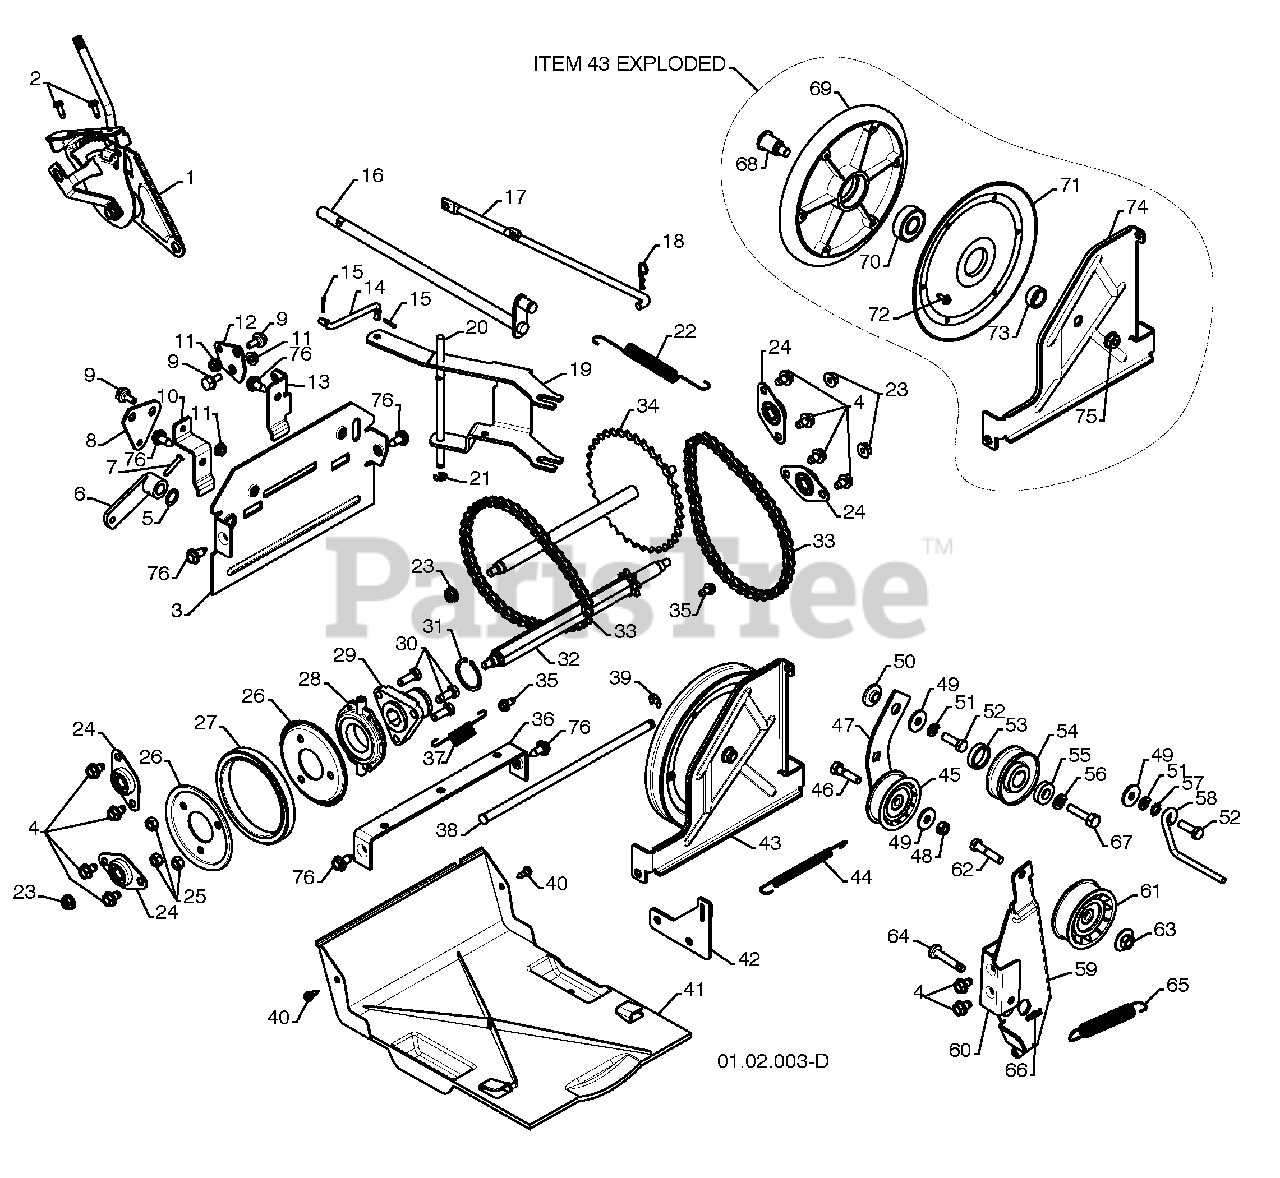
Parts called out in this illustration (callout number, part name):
1	SPEED SELECTOR ASSEMBLY
2	SCREW 10-24 X .625
3	END PLATE
4	SCREW 5/16-18 X .50
5	WASHER
6	CONTROL ARM
7	CLEVIS PIN
8	SHIFTER PLATE
9	SHOULDER BOLT
10	SHIFTER BRACKET
11	NUT 1/4-20
12	CLUTCH PLATE
13	CLUTCH BRACKET
14	SHIFTER LINK
15	RETAINER
16	CONTROL SHAFT
17	CLUTCH ROD
18	RETAINER
19	SHIFTER YOKE
20	PIVOT ROD
21	RETAINER
22	RETURN SPRING
23	NUT 5/16-18
24	BEARING
25	NUT 5/16-18
26	RUBBER WHEEL PLATE
27	RUBBER RING
28	BEARING
29	WHEEL HUB
30	SCREW 5/16-18-.875
31	RETAINER RING
32	HEX SHAFT
33	CHAIN
34	SPROCKET SHAFT
35	SCREW 1/4-20 X .50
36	SHIFTER BRACKET
37	SPRING
38	PLATE PIVOT ROD
39	E-RING .375
40	SHOULDER SCREW
41	BOTTOM PAN
42	SPRING BRACKET
43	DRIVE PLATE ASSEMBLY
44	IDLER SPRING
45	IDLER PULLEY
46	SCREW 5/16-18 X 1.25
47	IDLER ARM
48	NUT 5/16-18
49	WASHER
50	PIVOT BUSHING
51	LOCKWASHER 5/16
52	SCREW 5/16-18 X 1.00
53	SPACER
54	TRACTION PULLEY
55	WASHER 3/8
56	LOCKWASHER 3/8
57	LOCKWASHER
58	BELT GUIDE
59	IDLER ARM
60	IDLER BRACKET
61	IDLER PULLEY
62	SCREW 5/16-18 X 1.50
63	NUT 5/16-18
64	PIN IDLER PIVOT
65	IDLER SPRING
66	RETAINER
67	SCREW 3/8-24 X 1.375
68	PULLEY SHAFT
69	DRIVE PLATE
70	BEARING
71	PULLEY HALF
72	SCREW 10-24 X .50
73	SPACER BEARING
74	SWING PLATE
75	NUT 3/8-16
76	SCREW 5/16-18 X .750
